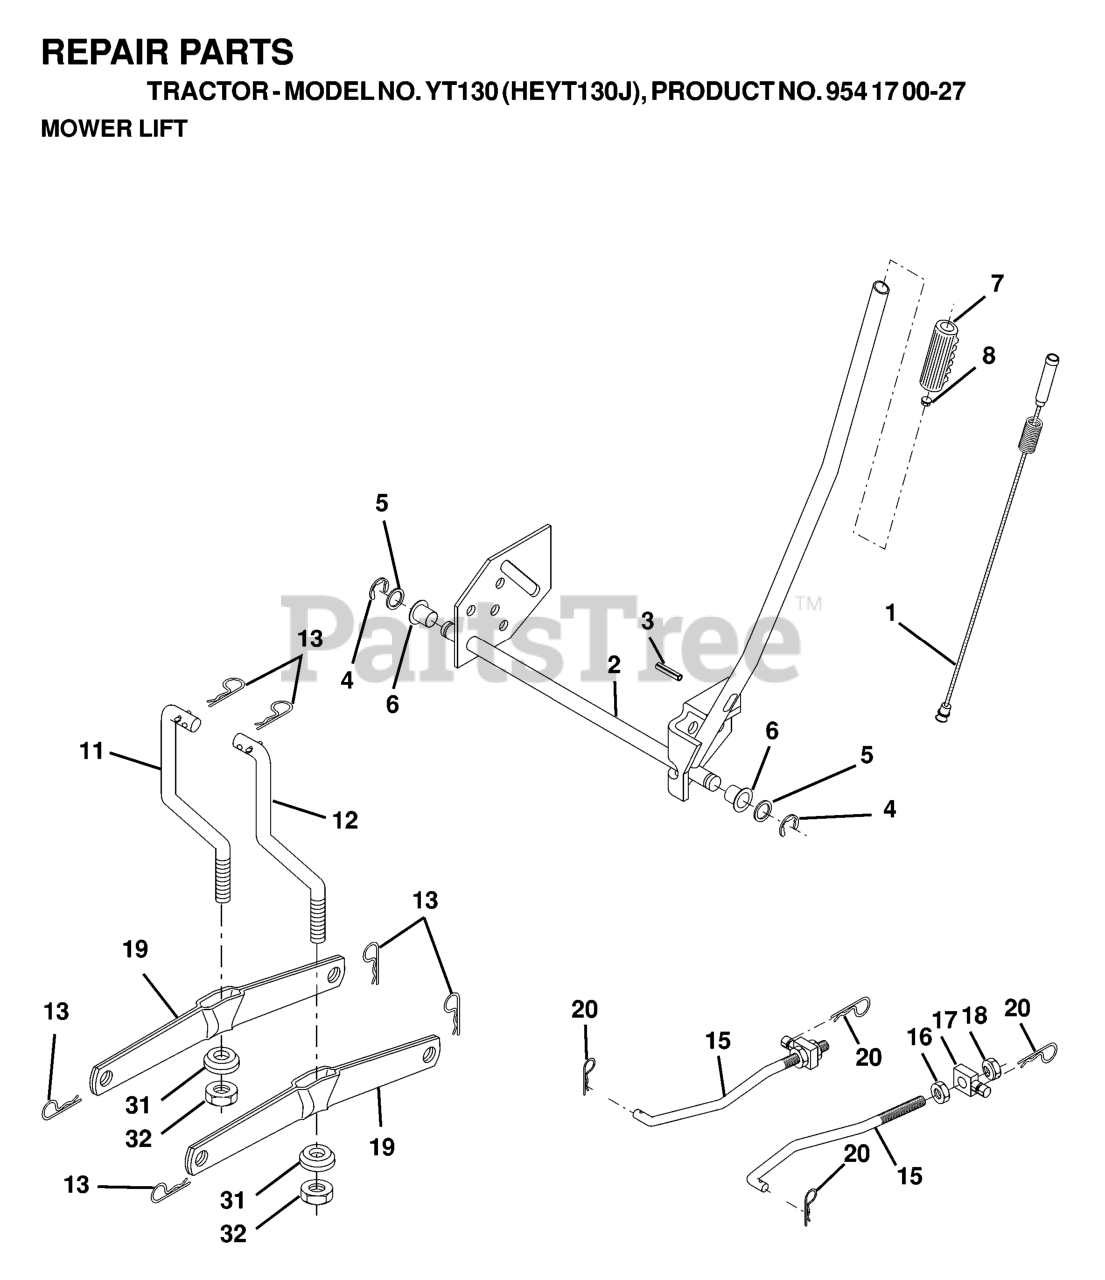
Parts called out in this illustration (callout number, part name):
1	WIRE ASM INNER W/ PLUNGER LT
2	SHAFT ASM R HANDLE
3	PIN GROOVE.
4	RETAINING RING LT
6	BEARING.NYLON
7	GRIP HANDLE
8	PLUNGER BUT KIT
11	LINK LIFT LH
12	LINK LIFT RH
13	RETAINER-SPRNG RB
15	LINK FRONT
16	NUT.HEX.JAM.1/2-13
17	TRUNION
18	NUT.LK.W/WSH.1/2.
19	ARM.REAR.SUSPENSION
20	SPRING RETAINER
31	BEARING PIVOT
32	NUT CROWNLOCK 3/8-24
